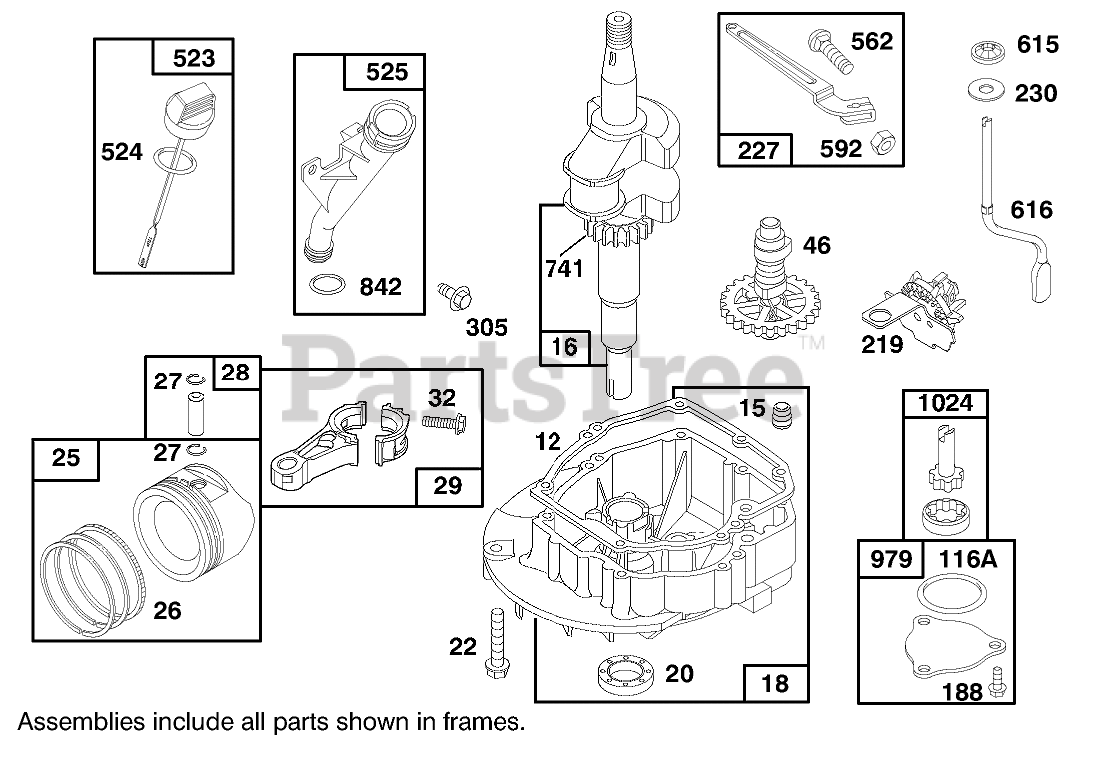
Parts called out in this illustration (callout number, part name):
12	ENGINE BASE GASKET
15	PLUG - PIPE
16	CRANKSHAFT
18	ENGINE SUMP
20	SEAL-OIL
22	SCREW - ENGINE BASE
25	STD PISTON ASSEMBLY
26	STD RING SET
27	PISTON PIN LOCK
28	PIN ASM - PISTON
29	CONNECTING ROD
32	SCREW - CONNECTING ROD
46	CAM GEAR
116A	O RING SEAL
188	SCREW - HEX HEAD
219	GOVERNOR/OIL SLINGER
227	GOVERNOR LEVER ASSEMBLY
230	WASHER
305	SCREW - HEX HEAD
523	DIPSTICK-OIL
524	O-RING
525	OIL FILLER TUBE
562	BOLT - GOVERNOR LEVER
592	NUT - HEX
615	FASTENER
616	GOVERNOR CRANK
741	TIMING GEAR
842	O-RING
979	OIL PUMP COVER
1024	OIL PUMP
